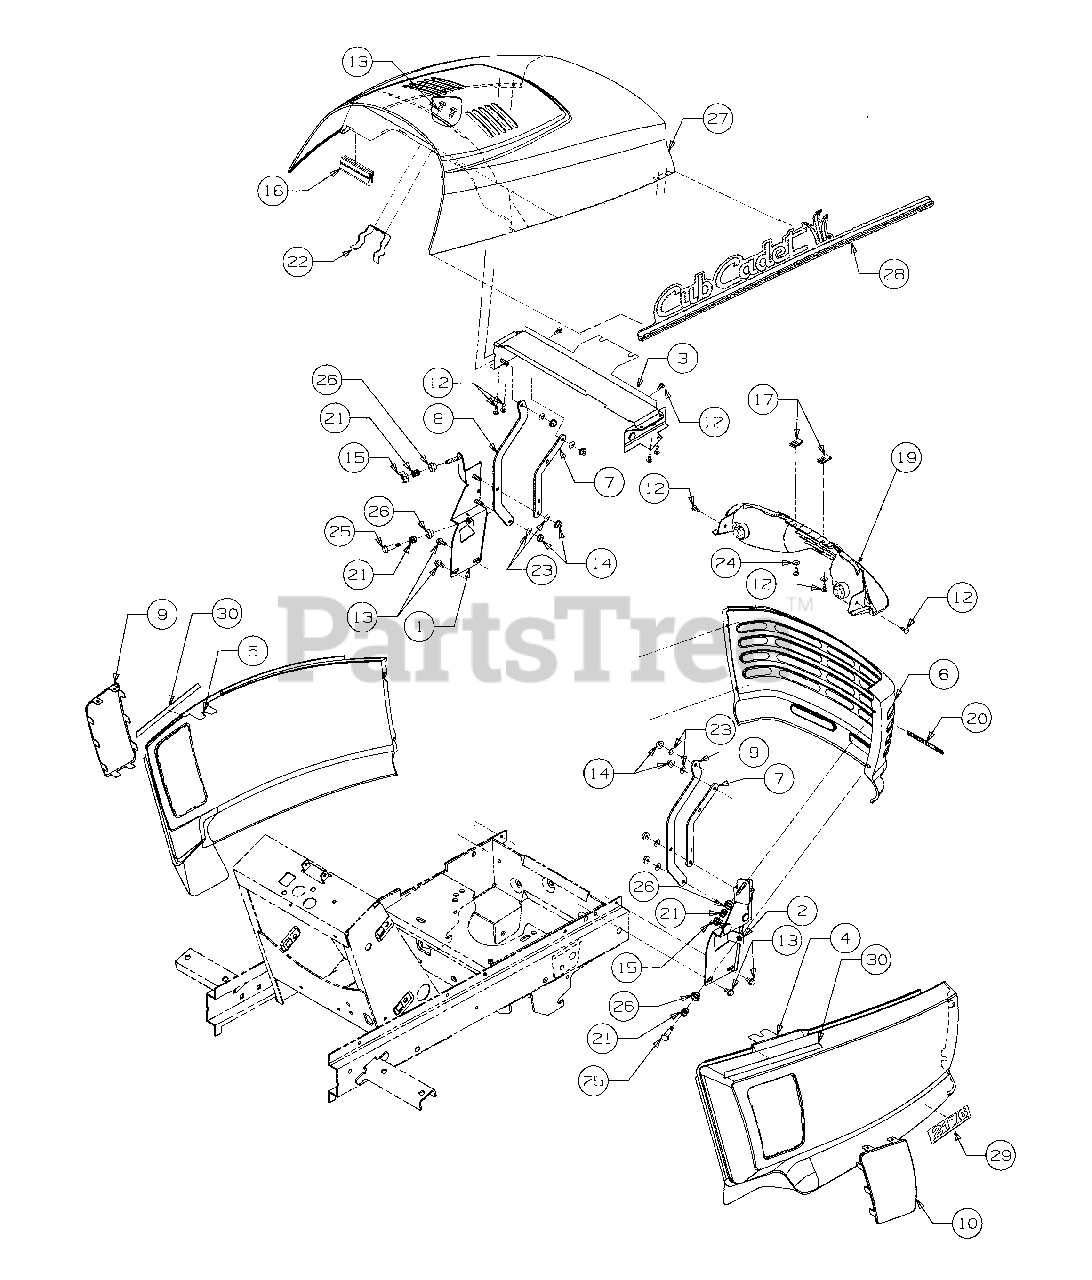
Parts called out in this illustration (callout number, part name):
1	Bracket, Grille LH
2	Bracket, Grille RH
3	Bracket, Upper Hood
4	Panel, RH Side
5	Panel, LH Side
8	Link, Long Hood
9	Screen, LH Panel
10	Screen, RH Panel
12	Screw, Truss Mach Tapp, #10 x .50
13	Screw, Hex Wash Hd Tapp, 1/4 x .50
14	Nut, Hex Flange Lock, 1/4-20
15	Nut, Wing, 1/4-20
16	Seal, Heat Baffle
17	Nut, U-Type Speed, #10
19	Headlight Assy
20	Graphic, Warning HOT
21	Spring, Compression, .50 OD x .50 Lg
22	Spring, Hood Latch
23	Washer, Spring, .265 x .562 x .025
24	Washer, Flat, .218 x .62 x .063
25	Bolt, Shoulder, .31 Dia x .75 Lg
26	Bushing, Tapered
27	Hood, Series 2000
28	Graphic, Hood RH
29	Graphic, 2176
30	Strip, Protective
